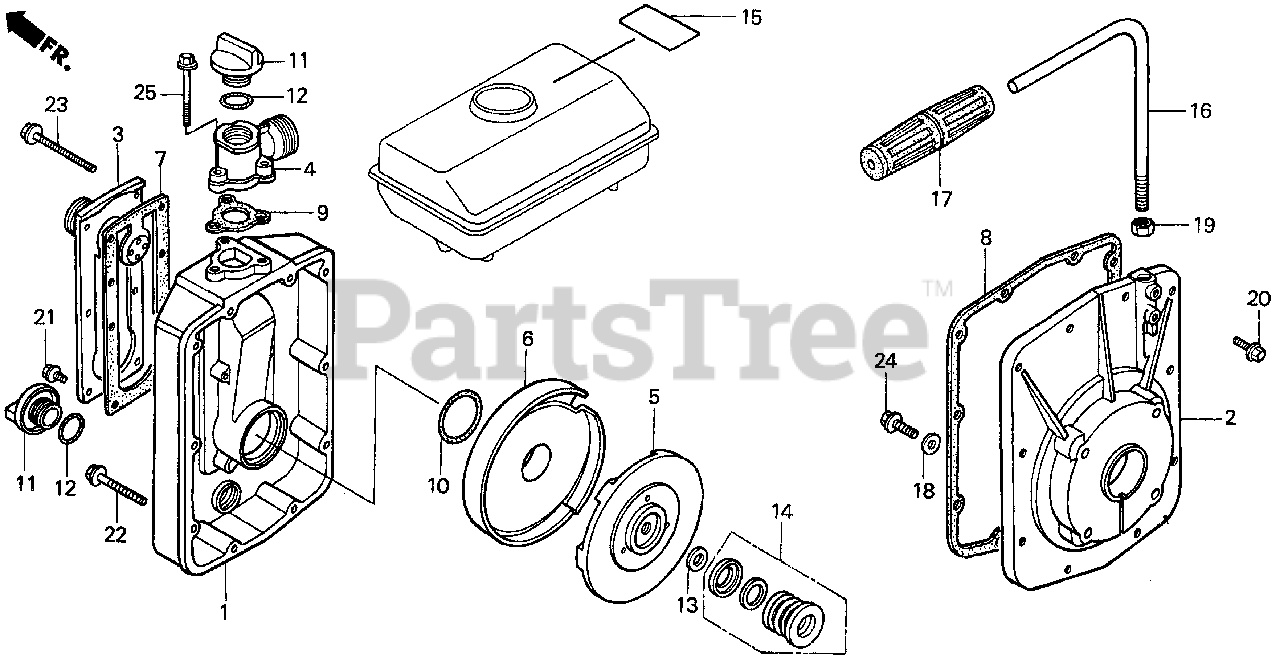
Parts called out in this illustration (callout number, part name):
2	PLATE, END
3	PLATE, SUCTION (NPTF)
4	OUTLET (NPTF)
6	CASE, VOLUTE
7	GASKET, SUCTION
8	GASKET, END PLATE
9	GASKET, OUTLET
10	RING A, SEAL
11	CAP, FILLER
12	RING, SEAL (B)
13	SHIM, ADJUSTER
14	SEAL ASSY., MECHANICAL
17	GRIP, HANDLE
18	WASHER (8MM)
19	NUT, HEX. (12MM)
20	BOLT, FLANGE (6X12)
21	BOLT, FLANGE (6X16)
22	BOLT, FLANGE (6X45)
23	BOLT, FLANGE (6X65)
24	BOLT, FLANGE (8X25)
25	BOLT, FLANGE (6X25)
